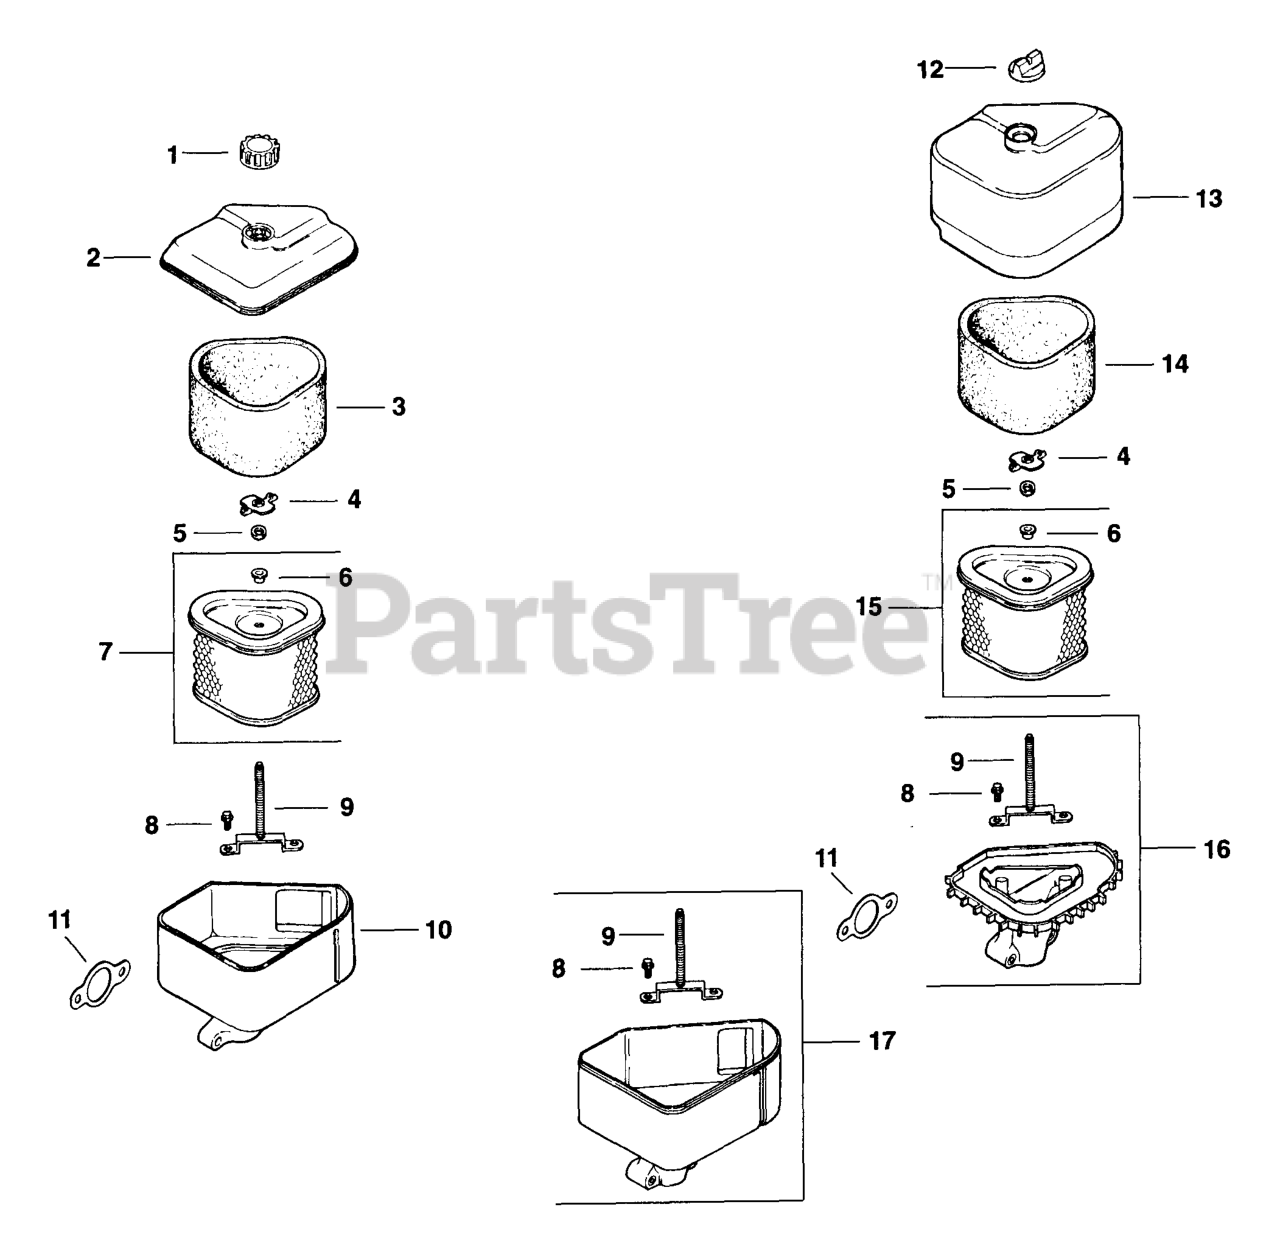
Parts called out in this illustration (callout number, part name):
1	Knob, Air Cleaner Cover
2	Cover, Air Cleaner
3	Precleaner
4	Nut, Wing
5	Washer, Plain 1/4"
7	Element, Air Cleaner
8	Screw, Hex. Cap #10 Hi-Lo Thread-Forming
9	Stud, Mounting Plate M6x1.0x79
9	Stud, Mounting Plate M6x1.0x75
9	Stud, Mounting Plate M6x1.0x66
10	Base, Air Cleaner
11	Gasket, Air Cleaner
12	Knob, Air Cleaner Cover
13	Cover, Air Cleaner
14	Precleaner
15	Element, Air Cleaner
16	Base, Air Cleaner
